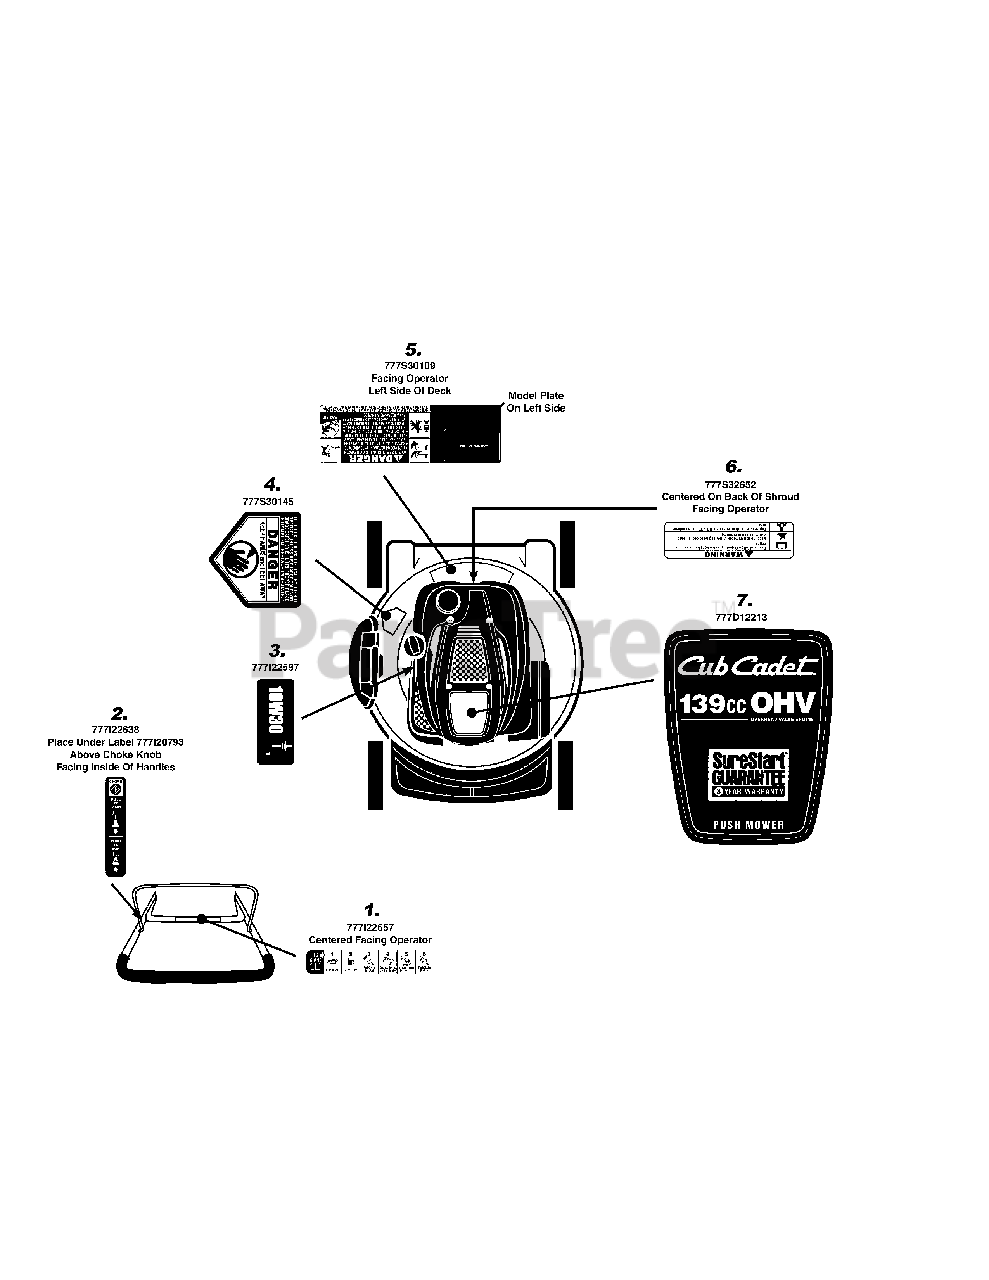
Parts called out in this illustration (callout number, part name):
1	LABEL-MOWER HANDLE
2	LABEL-MOWER HANDLE:CHOKE START/RUN
3	LABEL:MOWER SHROUD
4	LABEL
5	LABEL-MOWER DANGER
6	LABEL:MOWER:ENGINE SHROUD
7	LABEL-139CC SHROUD OHV PUSH MWR
